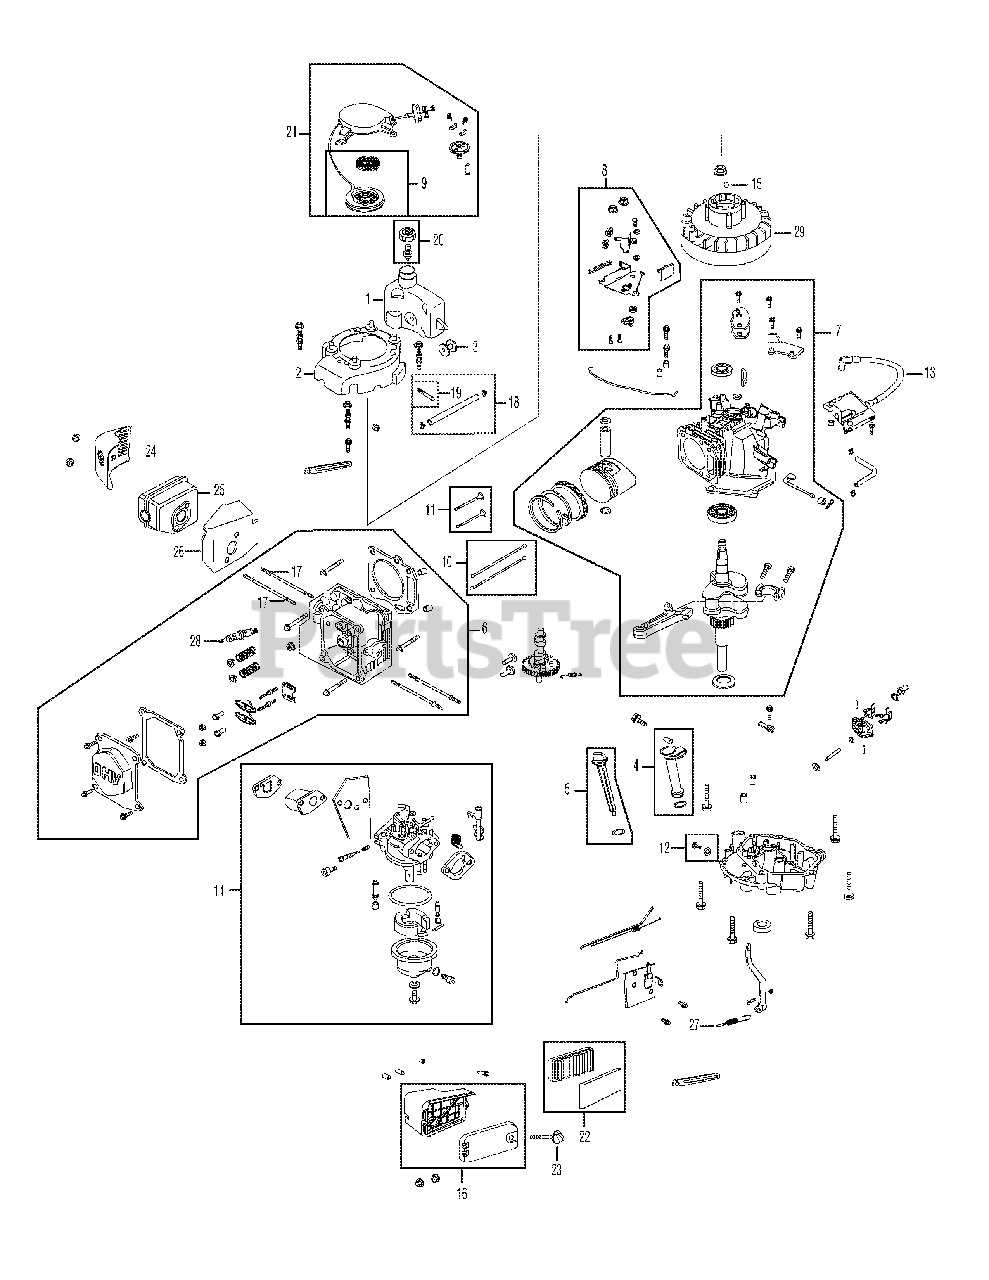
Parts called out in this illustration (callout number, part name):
1	Fuel Tank
2	Flywheel Shroud
2	Screw
3	Rubber Fuel Tank Mounting Washer
4	Oil Filler Tube Assembly
5	Dipstick Assembly
6	Cylinder Head Complete
7	Short Block Assembly
8	Stop Switch and Brake Assembly
9	Recoil Spring and Pulley Assembly
10	Push Rod Kit
11	Valve Kit
12	Oil Drain Plug and Washer Assembly
13	Ignition Coil
14	Carburetor Assembly
15	Flywheel Key
16	Air Cleaner Housing Assembly Complete
17	Muffler Stud Assembly
18	Fuel Line Kit - Inc. hoses, clamps & filter
19	Fuel Filter
20	Fuel Cap Assembly
21	Recoil Starter Assembly
22	Air Cleaner Kit
23	Air Cleaner Thumb Screw
24	Muffler Guard
25	Muffler
26	Muffler Gasket /Heat Shield
27	Governor Return Spring
28	Spark Plug
29	Flywheel
